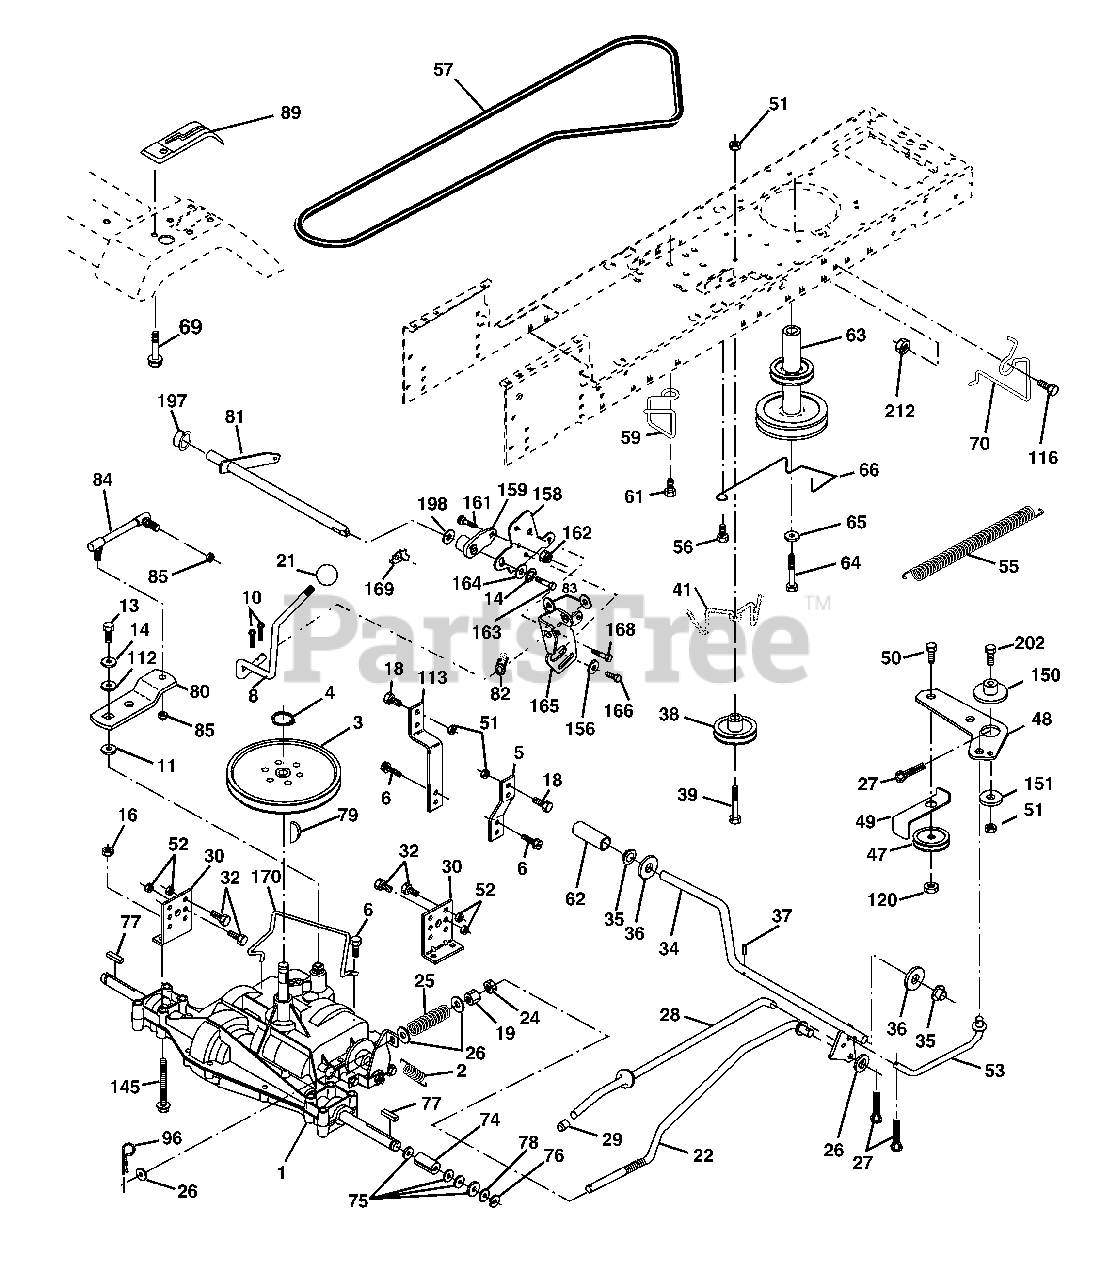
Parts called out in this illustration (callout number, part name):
2	Spring Return Brake T/a Zinc
3	Pulley Transaxle 18" tires
4	Ring Retainer # 5100-62
5	Strap Torque 30 Degrees
6	Screw 5/16-18 X 3/4
8	Rod Shift Fender Adjust Lt
10	Pin Cotter 1/8 X 1 Cad
11	Washer Plate Shf 388 Sq Hole
13	Bolt 1/4-28 Unf Gr 8 W/Patch
14	Washer Lock Hvy Helical
16	Nut Lock Hex w/ins 5/16-18
18	Bolt, Fin Hex 3/8-16 UNC x 1 Gr. 5
19	Nut Lock 3/8-16 Unc
21	Knob
22	Rod Brake Blk Zinc 26 840
24	Nut Hex Jam 3/8-16 Unc
25	Spring Rod Brake 2 00 Zinc
26	Washer 13/32 X 13/16 X 16 Ga
27	Pin Cotter 1/8 X 3/4 Cad
28	Rod Brake Parking LT/YT
29	Cap Brake Parking
30	Bracket Mtg Transaxle
32	Bolt Hex Hd 5/16-18unc X 3/4
34	Shaft Asm Pedal Foot
35	Bearing Nylon Blk 629 Id
36	Washer 21/32 X 1 X 16 Ga
37	Pin Roll 3/16 X 1"
38	Pulley Composite Flat
39	Bolt Fin Hex 3/8-16 unc X 3
41	Keeper Belt Flat Idler
47	Pulley Idler V Groove Plastic
48	Bellcrank Asm
49	Retainer Belt Style Spring
50	Bolt Carr. Sh. 3/8-16 x 1-1/2 Gr. 5
51	Nut Crownlock 3/8-16 Unc
52	Nut Crownlock 5/16-18 Unc
53	Link Clutch
55	Spring Return Clutch 6 75
56	Screw 3/8-16 x 1-1/4
57	V-Belt Ground Drive 95 25
59	Keeper Belt Span Ctr
61	Screw 3/8-16 x .875
62	Cover Pedal Blk Round
63	Engine Pulley
64	Bolt Hex
65	Washer Lock Hvy Hlcl Spr 7/16
66	Keeper Belt Engine Foolproof
69	Screw Hex wsh Hi Lo 1/4 x 1/2 unc
70	Guide Belt Mower Drive RH
74	Spacer Axle
75	Washer 25/32 X 1 1/4 X 16 Ga
76	E-ring #5133-75
77	Key Square 2 0 X 1845/ 1865
78	Washer 25/32 X 1-5/8 X 16 Ga
79	Key Woodruff #9 3/16 x 3/4
80	Arm Shift
81	Shaft Asm Cross Tapered PMST/20
82	Spring Torsion T/a
83	Washer 17/32 X 3/4 X 16 Ga
84	Link Transaxle PMST/18" Zinc
85	Nut Lock Center 1/4 - 28 FNTHD
89	Console Shift STLT
96	Retainer Spring 1"
112	Washer 9/32 x 3/4 x 10 Ga.
113	Strap Torque LT
116	Bolt Rdhd Sq Neck 3/8-16 x 1
120	Nut Lock Flg. 3/8-16 Unc
145	Bolt Hex FLGHD 5/16-18 Gr. 5
150	Spacer Retainer
151	Washer 13/32 x 2 x 10
156	Washer Srrted 5/16ID x 1.125
158	Bracket Shift Mount
159	Hub Shift
161	Bolt Rdhd Sqnk 1/4-20 x 3/4 Gr
162	Nut Crownlock 1/4-20 Unc
163	Bolt Hex Fin 1/4-20 Unc x 1 Gr 5
164	Washer 5/8 x .281 x 10 Ga
165	Bracket Pivot Lever
166	Screw 5/16-18 x 5/8
168	Bolt Shoulder 5/16-18 x .561
169	Plate Fastening
170	Keeper Belt Transaxle Gear
197	Nyliner Snap-In
198	Washer Nyliner
202	Bolt Rd Hd 3/8-16 Unc x 1-3/4 Gr. 5
212	Nut Hex flange Lock
